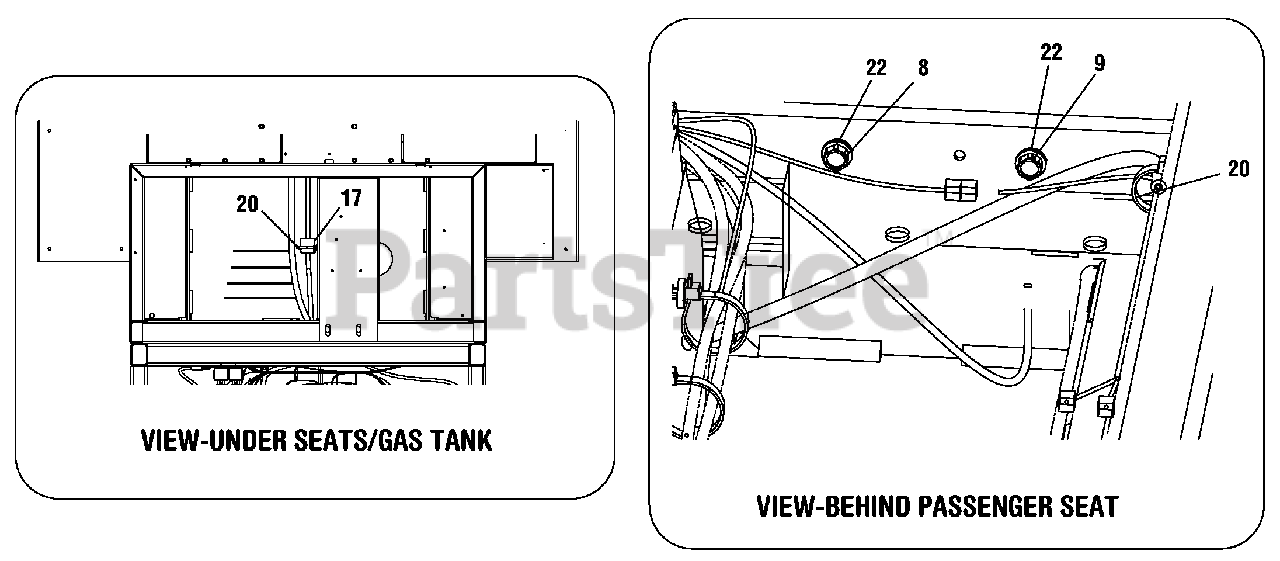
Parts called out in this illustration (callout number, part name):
8	Screw, Self-tapping, 1/4-20 x 1.000
9	Screw, #10-24 x 0.75
17	Control, Reverse
20	Cable Tie, .19 x 8.39 Tree Mount
22	Lock Washer, 1/4
